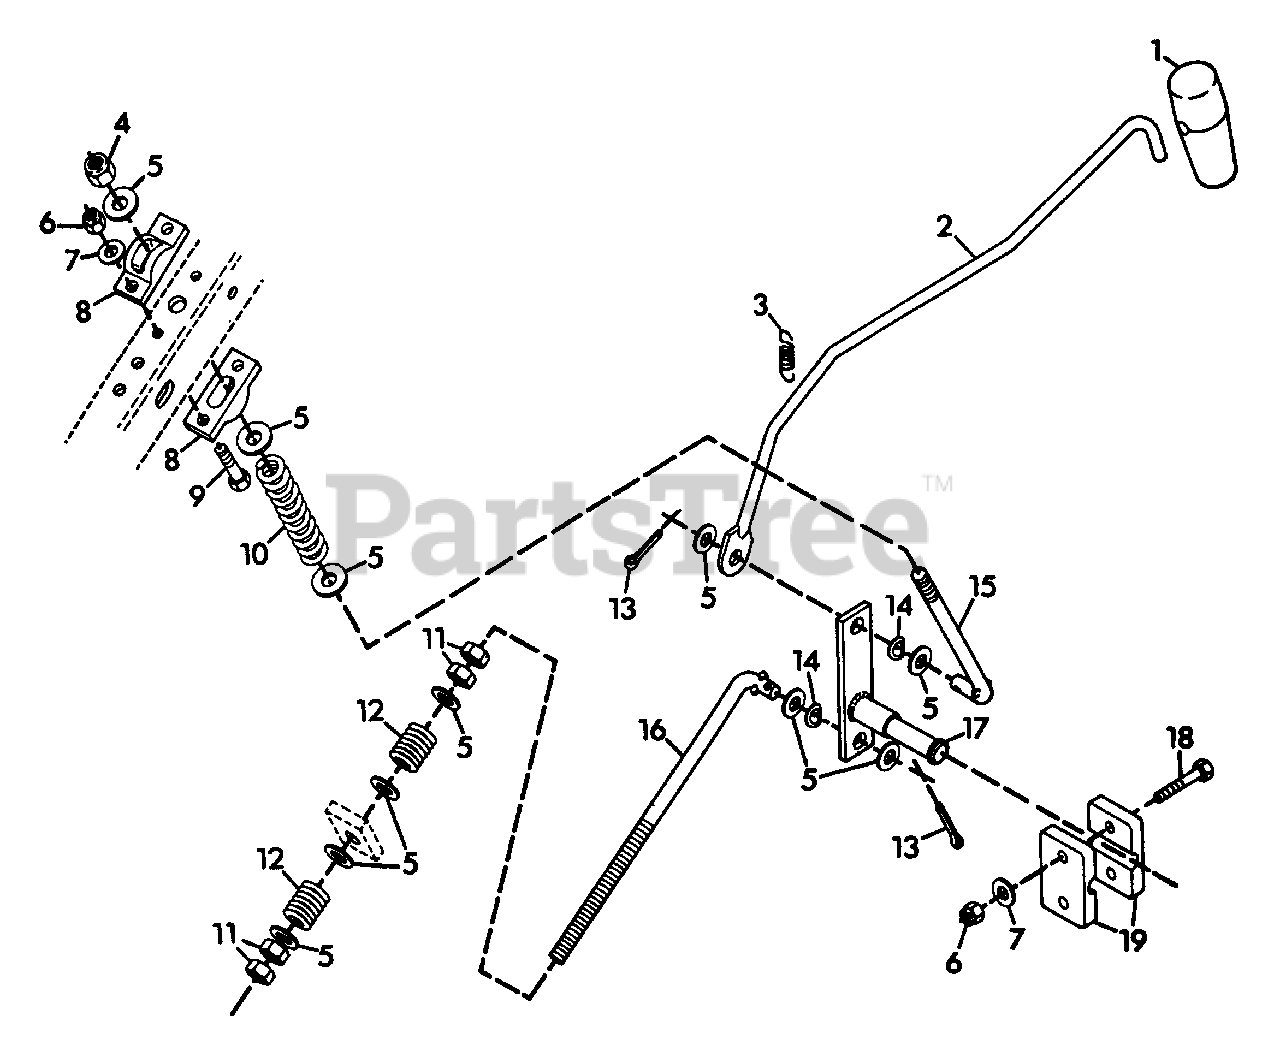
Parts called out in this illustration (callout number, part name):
1	Handle, Rubber Shifter
2	Rod, Shifter
3	Spring, Extension .50 x 1.25
4	Nut, Lock 3/8-16
5	Washer, Flat .406 x .812 x .065
6	Nut, Lock 1/4-20
7	Washer, Flat .281 x .625 x .065
8	Cam, Shifter
9	Bolt, Hex 1/4-20 x 1.00
10	Spring, Compression .720 x2.75
11	Nut, Jam 3/8-16 Hex
12	Spring, Compression 1.0 x .78 x .338
13	Pin, Cotter .125 x .750
14	Washer, Spring .375 I.D.
15	Link, Shifter Stop
16	Link, Shifter
17	Weldment, Shifter Crank
18	Bolt, Hex 1/4-20 x 1.50
19	Block, Shift Lever
